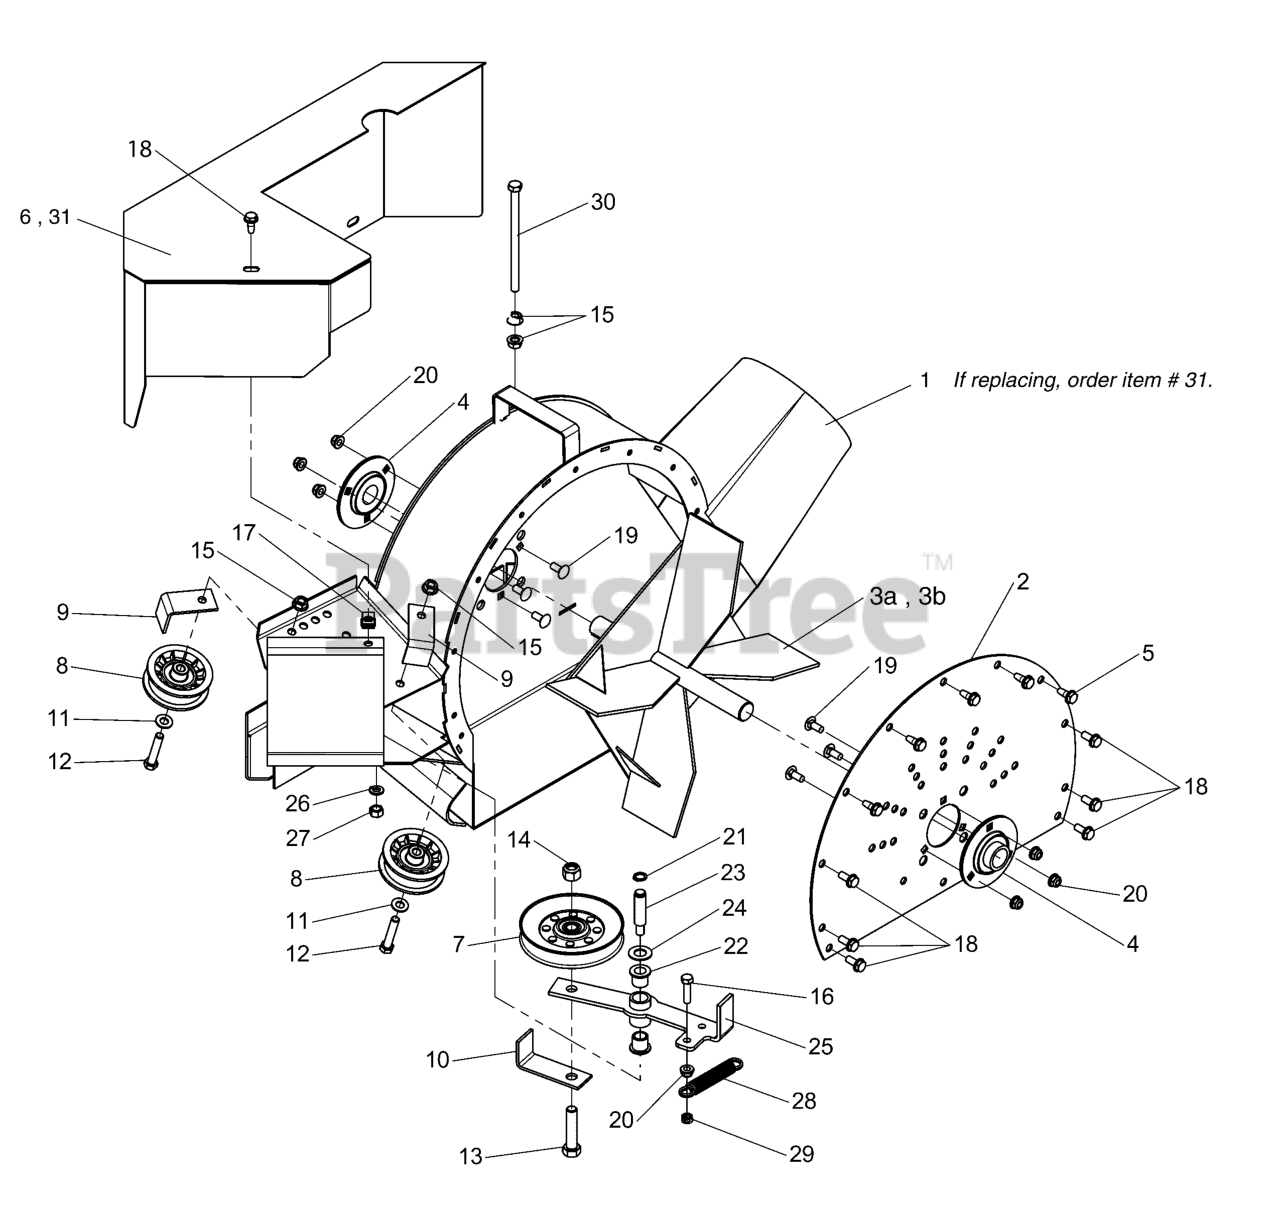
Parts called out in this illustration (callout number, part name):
1	WELD, BLOWER HOUSING - FAST VAC - BLK
2	PLATE, BACK - BLK
4	BEARING, FLANGE, 1" Bore
5	BOLT, 5/16-18 X 3/4" Self Tap
6	WELD, BELT GUARD, BLOWER - BLK
7	PULLEY-IDLER-V, 4.85OB, .506 ID, ,94W, STL
8	PULLEY, IDLER, 2.75"OD X .37"ID, INSERT
9	KEEPER, BELT - BLK
10	RETAINER, BELT - BLK
11	WASHER, 3/8 SAE
12	HHCS, 3/8-16 X 2.00, GR5, ZINC/CLEAR
13	BOLT, 1/2-13 X 2-1/4" GD5 CZ
14	NUT, 1/2-13 HEX NYLON LOCK
15	NUT, 3/8-16 Hex Large Serrated Flange
16	BOLT, 5/16-18 X 1-1/4" GD5 YZ
17	BODY CLIP, 5/16-18-7GA MATERIAL
18	BOLT, 5/16-18 X 5/8" Self Lock
19	BOLT, 5/16-18 X 3/4, CARRIAGE, GD5, CZ
20	NUT, 5/16-18 HEX NYLOCK FLANGE NUT
21	RETAINING RING, 1/2"
22	FLANGE BEARING, 9/16"
23	IDLER STUD
24	FLAT WASHER, 9/16" Narrow
25	WELD, IDLERARM, FAST-VAC - BLK
26	WASHER, 3/8" SPLIT LOCK
27	NUT, 3/8-24 HEX (SV)
28	SPRING, Extension
29	NUT, 5/16-18 Hex Center Lock
30	BOLT, 3/8-16 X 6" GD5 CZ
31	WELD, Fast-Vac Guard - BLK
